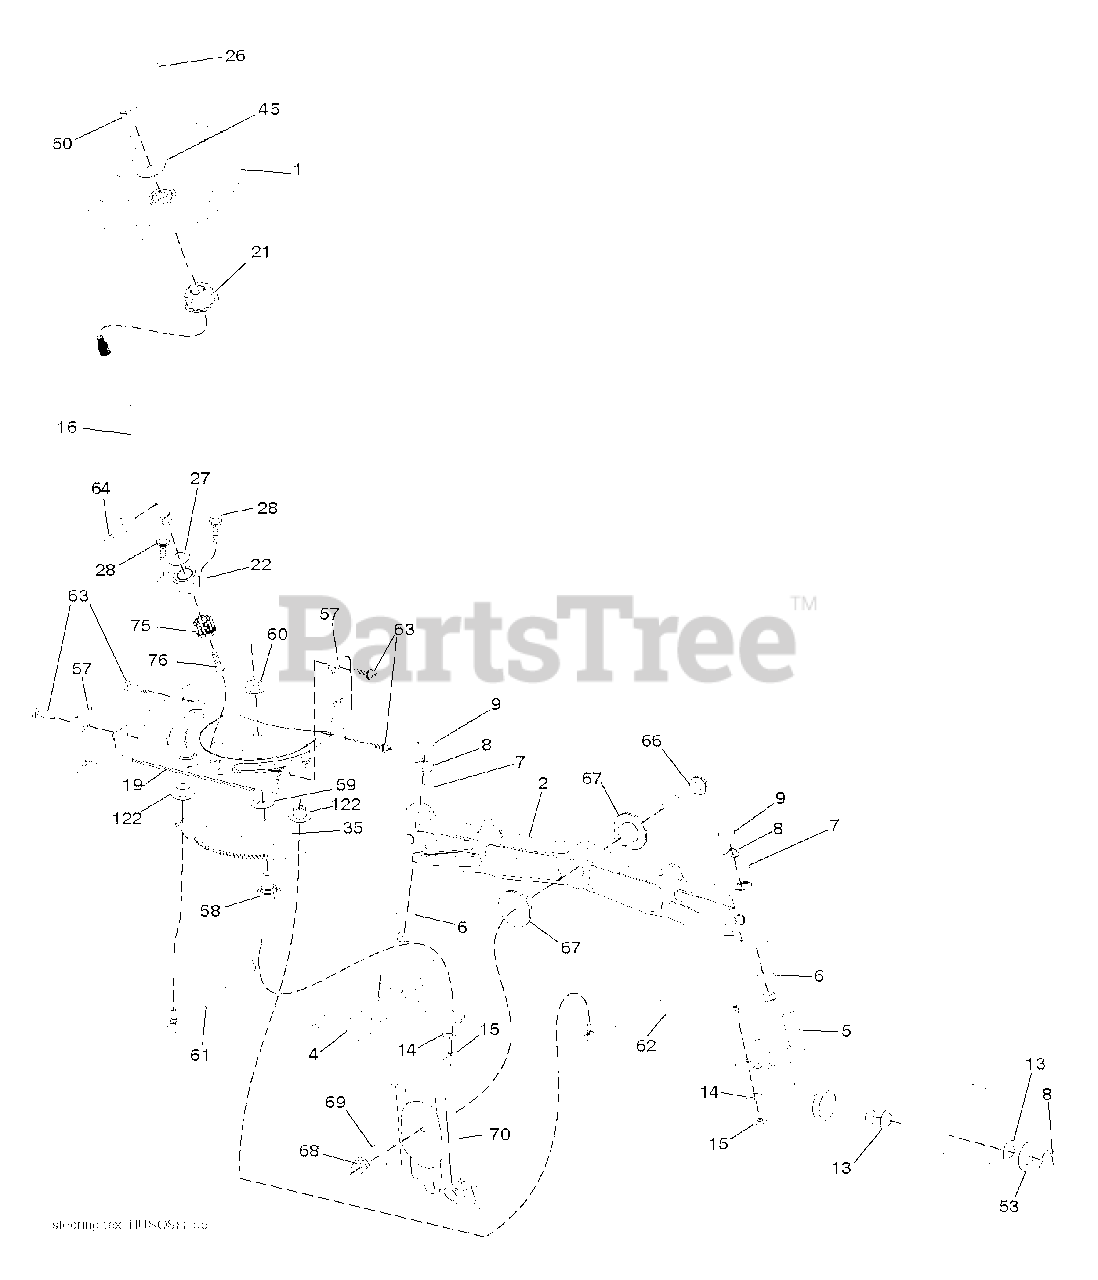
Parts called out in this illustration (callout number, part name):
1	WHEEL.STEER.HUSQ.SR.498.OVMLD
2	AXLE.CAST.IRON
4	SPINDLE.WELDED.LH.15"TEX
5	SPINDLE.WELDED.RH.15"T
6	THRUST WASHER
9	CAP.SPINDLE.BLACK
14	SLW 3/8 STD
15	NUT CROWNLOCK 3/8-24
16	SHAFT.STEER.2HIGH.SPLND.PLATED
19	PLATE.STEER.DDL.NLT/NG
21	ADAPTER.WHEEL.STEER.SPLND.ALUM
22	BEARING.SHAFT.STEER.LOWER.625
26	INSERT.CAP.WHL.STRG.HUSQ.PREM
28	SCREW, 3/8-16X3/4
35	GEAR.SECTOR.PLATE.DDL.
45	WASHER.3/8ID.2-3/8OD.12GA.PLTD
50	NUT LOCK FLG 3/8-16 UNC
53	WASHER.HARDENED
57	BRACKET.UPSTOP.TEX
58	BOLT.SHOULDER.SECTOR.P
59	WASHER.THURST.SECTOR.S
60	NUT FLANGE LOCK 5/8-11
61	LINK.ASM.DRAG.ADJUST.LH.PLATED
62	LINK.ASM.DRAG.ADJUST.RH.PLATED
63	SCREW
64	RETAINER.CLIP.SPRING.S
66	BOLT HEX FGHD 7/16-14 X 3 SERR
67	BUSHING.PM.FRONT AXLE
68	NUT.LOCK.FLANGE.7/16
69	WASHER.1.5X.505X.118
70	BRACKET.FRT.DECK.SUSP.RR.MT431
75	PINION.ZINC PLATED
76	SCREW HEAD SOCKET LRVB
122	CAP.GEAR.SECTOR.TEX
